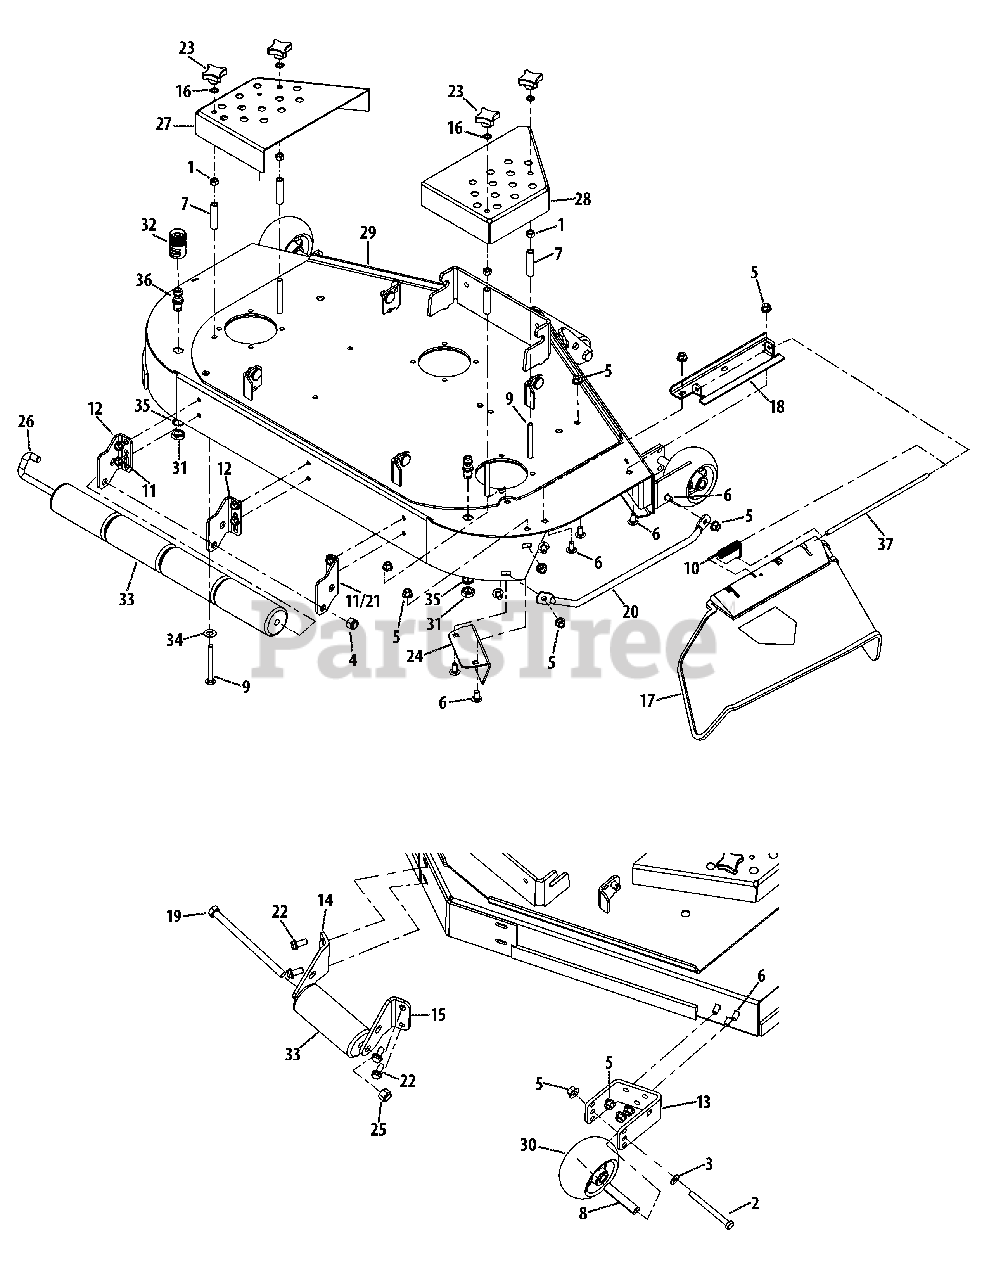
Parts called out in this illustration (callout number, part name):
1	Nut, 3.8-16
2	Hex Screw, 3.8-16 x 4.00
3	Washer, .406 x .813 x .063
4	Nut, 1.2-13
4	Hex Lock Nut, 1.2-13
5	Flange Counterlock Nut, 3.8-16
6	Carriage Bolt, 3.8-16 x .75
7	Spacer, .400 x .560 x 2.45
8	Spacer, .390 x .620 x 3.04
9	Carriage Bolt, 3.8-16 x 3.50
10	Torsion Spring, .639 x 2.16 x .12
11	Flange Screw, 3.8-16 x .500
12	Roller Mount Bracket
13	Anti-Scalp Front Mount Bracket
14	LH Front Roller Mount Bracket
15	RH Front Roller Mount Bracket
16	Washer, .398 x .694 x .032
17	Chute Deflector
18	Chute Deflector Bracket
19	Hex Screw, 1.2-20 x 7.50
20	Finger Guard
21	RH Roller Mt. Brkt. (44 & 48 Deck)
22	Flange Screw, 3.8-16 x .875
23	Plastic Knob, 3.8-16
24	Micro Chute Baffle
25	Nut, 1.2-20
26	J-Hook
27	LH Belt Cover
28	RH Belt Cover
29	Deck Assembly (44 Inch)
29	Deck Assembly (48 Inch)
29	Deck Assembly (54 Inch)
31	Hex Nut
32	Water Nozzle Adapter
33	Front Roller
34	Flat Washer, .510 x 1.00 x .060
35	Lock Washer, 17 x 23.8 x 1.95
36	Water Deck Nozzle
37	Chute Deflector Rod
